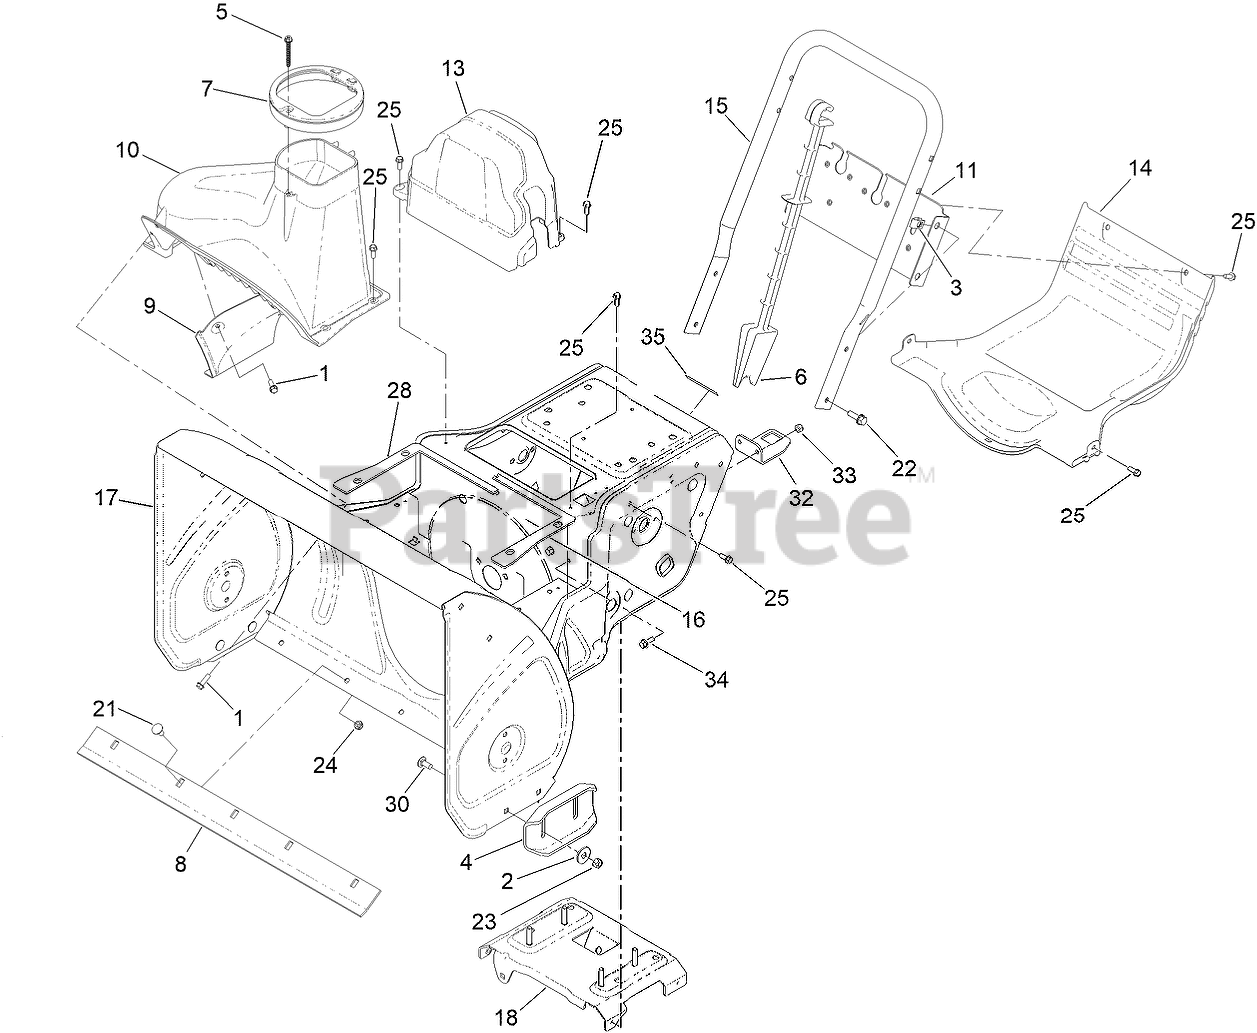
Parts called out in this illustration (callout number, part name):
1	SCREW-HWH
2	WASHER
3	NUT-U
5	SCREW-HWH, PLASTITE
6	STICK-CLEANOUT
7	GUIDE-CHUTE
8	SCRAPER-26 INCH
9	COVER-LINER
11	BRACE-FRAME
13	COVER-BELT
14	COVER-LOWER
15	HANDLE-LOWER, CTS
16	SEAL-HOUSING, LH
17	FRAME ASM
18	BRACE-FRAME
21	SCREW-CARR
22	SCREW-HHF
23	NUT-LOCK, NI
24	NUT-LOCK, NI
25	SCREW-HWH
28	SEAL-HOUSING, RH
30	SCREW-CARR
32	BRACKET-POST, CHUTE
33	SCREW-HHF
34	NUT-HEX
35	DECAL-WARNING
